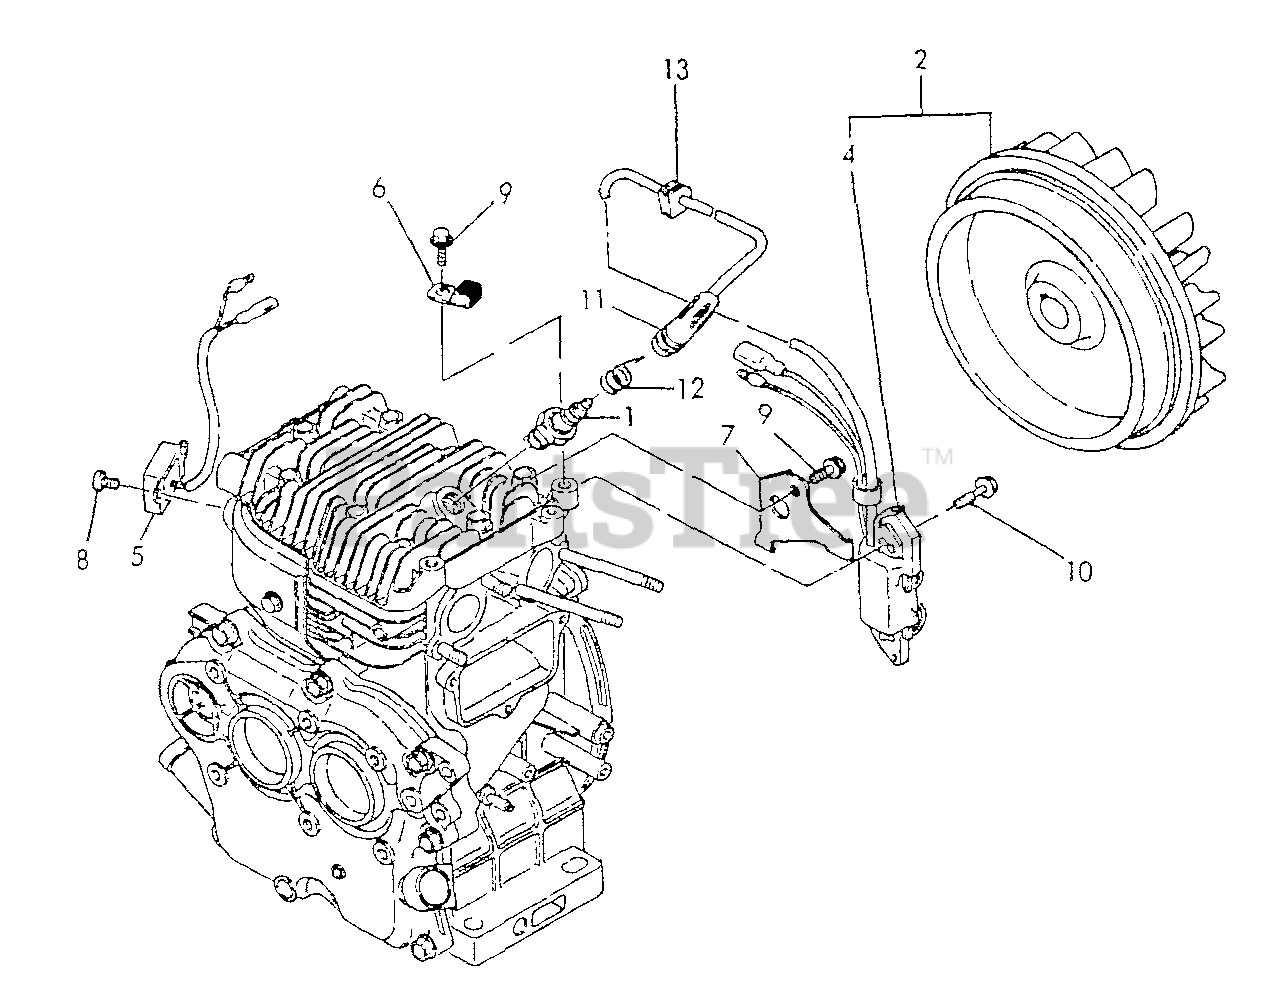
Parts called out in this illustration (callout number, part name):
1	SPARK PLUG
2	FLYWHEEL W/MAGNET
4	COIL, IGNITION
5	IGNITER
6	CLAMP
7	CLAMP
8	SCREW - 5×10
9	BOLT - 6×8 -- PLATED
10	BOLT - 6×30
11	CAP, PLUG
12	TERMINAL, SPARK PLUG CAP
13	GROMMET
